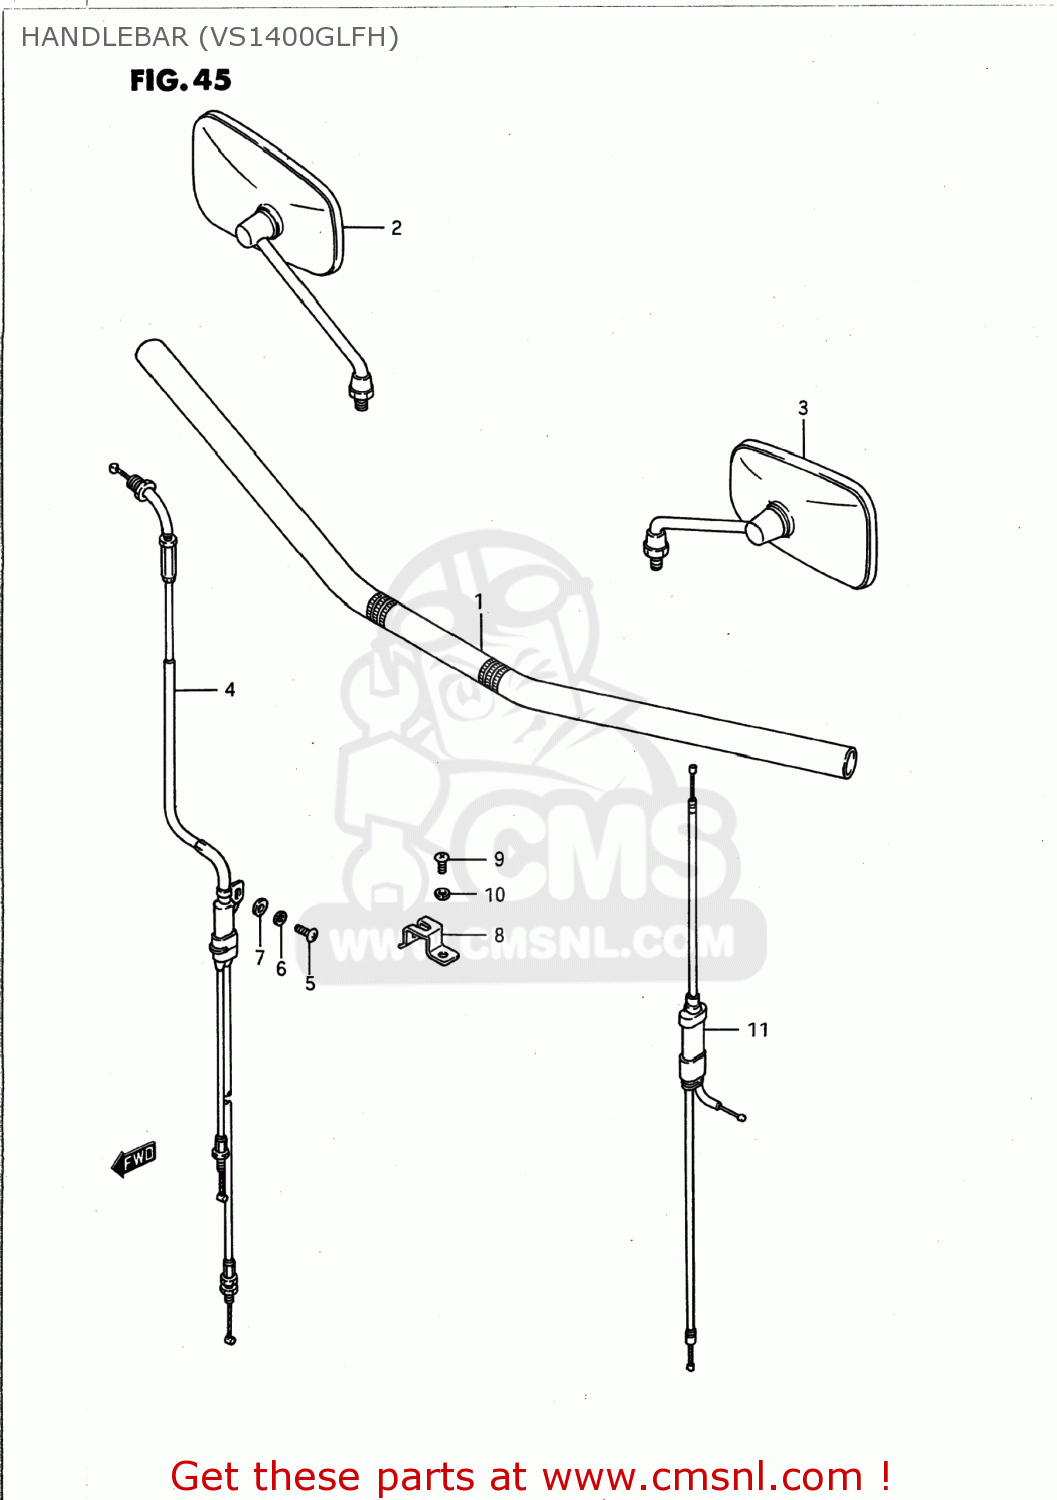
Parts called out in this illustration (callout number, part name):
1	HANDLEBAR
2	MIRROR ASSY,RR VIEW,R
3	MIRROR ASSY,RR VIEW,L
4	CABLE ASSEMBLY,THROTTLE
5	SCREW
6	LOCK WASHER
7	WASHER
8	CLAMP,THROTTLE CABLE CONNECTOR
9	SCREW
10	LOCK WASHER
11	CABLE ASSEMBLY,STARTER
